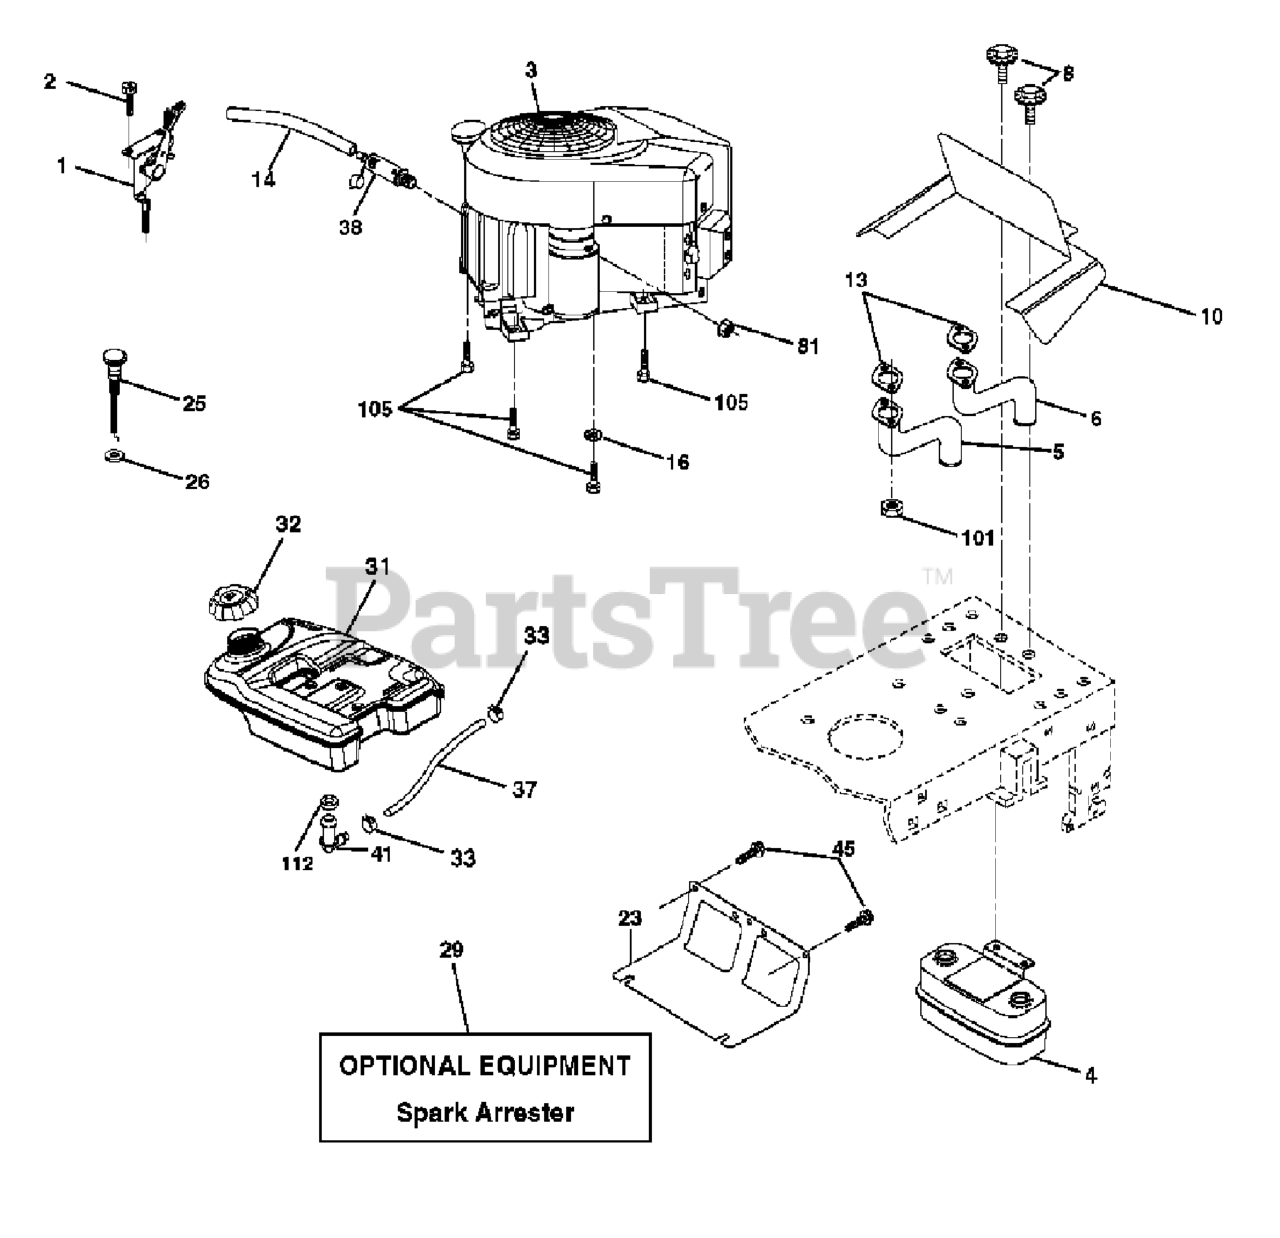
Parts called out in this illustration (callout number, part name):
1	CONTROL, THROTTLE
2	SCREW
4	MUFFLER.TWIN.CYL.LOW.TONE
5	EXHAUST TUBE LH KAWI
6	EXHAUST TUBE RH KAWI
8	BOLT.5/16-18UNCX3/4 W/SEMS.BLK
10	RP SHIELD HEAT MUFFLER
13	Gasket Muffler
14	Tube Drain Oil Easy
16	LOCKWASHER
23	SHIELD.BROWNING.DBR.GUARD
25	CHOKE CONTROL
26	Nut, Keps 3/8-24 Unf
29	KIT.SPARK ARRESTOR 794945 B&S
31	4.0 REAR FUEL TANK
32	TANK CAP
33	HOSE CLAMP
37	REPL BY 532 00 85-43
38	Plug Drain Oil
41	STEM FUEL TANK
45	SCREW, 3/8-16X3/4
81	NUT
101	FLANGE NUT
105	SCREW 3/8-16X1
112	BUSHING OUTLET T
